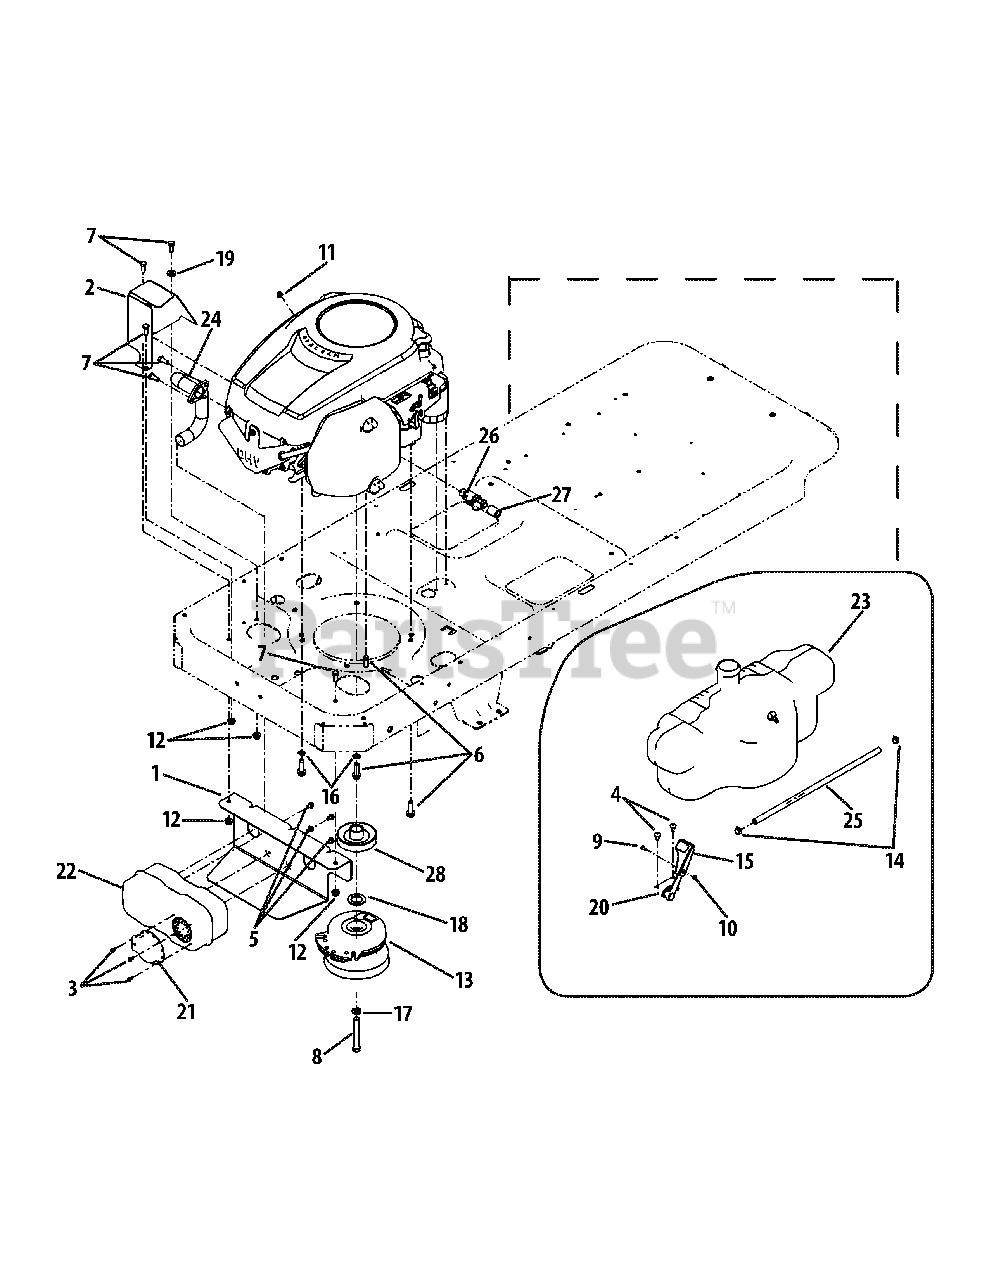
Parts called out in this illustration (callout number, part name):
1	Muffler Mounting Bracket
2	Muffler Tube Heat Shield
3	Hex Washer Head Screw, #8-18 x .5
4	Hex Washer Head Screw, 1/4-14 x
5	Hex Washer Head Screw, 1/4-20 x .5
6	Hex Washer Head Screw, 3/8-16 x 1.25
7	Hex Cap Screw, 5/16-18 x .75
8	Hex Cap Lock Screw, 7/16-20 x 3.25
9	Truss Head Machine Screw, #8-32 x .375
10	Hex Nut, #8-32
11	Hex Sems Nut, 1/4-20
12	Hex Insert Flange Lock Nut, 5/16-18
13	Electric PTO Clutch Assembly
14	Hose Clamp
15	Throttle Control Knob
16	External Tooth Lock Washer, 3/8
17	Lock Washer, 7/16
18	Flat Washer, 1.031 x 1.62 x .095
19	Flat Washer, .344 x .75 x .12
20	Throttle Cable, 39.0 Lg
21	Muffler Deflector
22	Muffler
23	Fuel Tank
23	Fuel Tank Bushing
23	Fuel Pick-Up Fitting
23	Fuel Cap
24	Exhaust Pipe
25	Low Permeation Fuel Hose
26	Oil Drain Valve
27	Oil Drain Extension Hose
28	Drive Pulley
